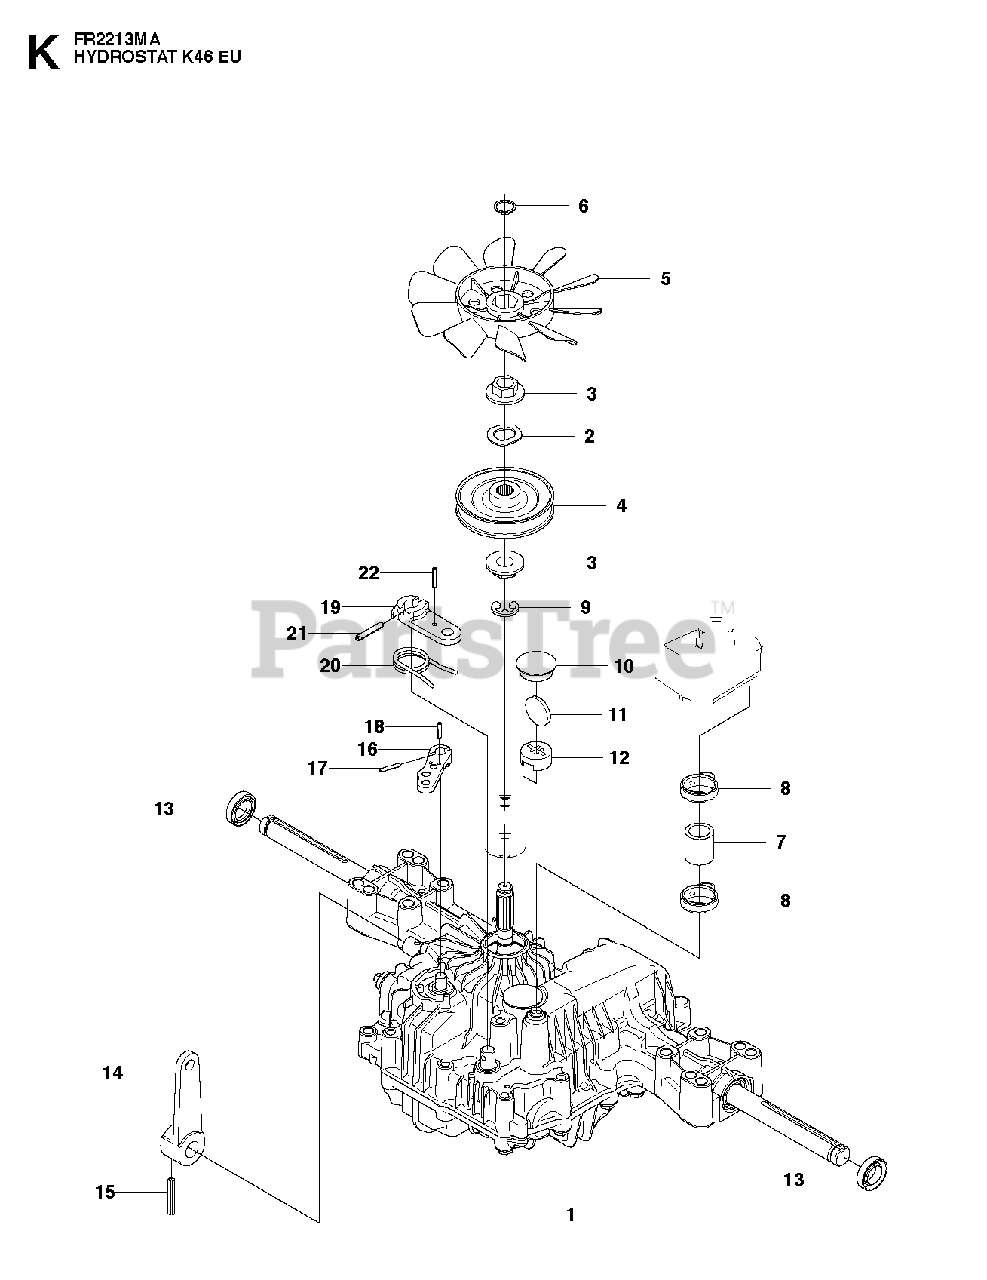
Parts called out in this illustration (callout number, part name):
1	HYDROSTAT
2	WASHER **
5	FAN
6	RETAINING RING **
8	CLAMP
9	CLIP
10	PLUG
11	MAGNET
12	MAGNET HOLDER
13	SEALING
14	CONTROL LEVER
15	PIN
16	ARM
17	PIN
18	PIN
19	ARM
20	RETURN SPRING
21	PIN
22	PIN
